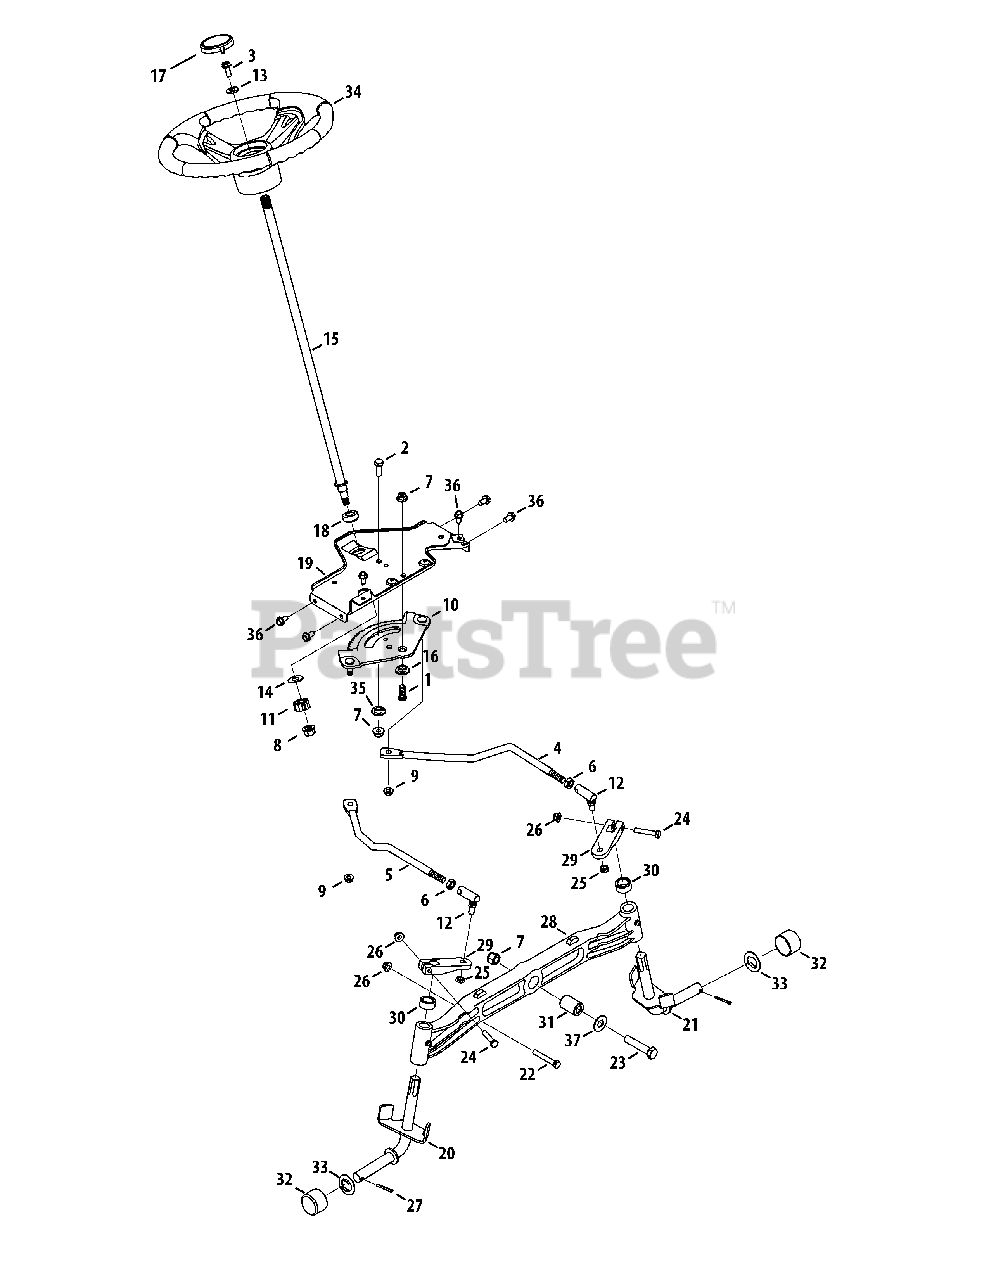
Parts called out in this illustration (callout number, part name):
1	Hex Screw, 3/8-16, 1.00, Gr5, Spec
2	Hex Screw, 3/8-16, 1.00, Gr5, Std
3	Hex Screw, 5/16-18, .875, Gr5, Lock
4	Link, Drag LH
5	Link, Drag RH
6	Nut, Jam, 7/16-20, Gr2
7	Nut, Flange Lock, 3/8-16, Grf,
8	Nut, Flange Lock, 7/16-20, Grb, Lock
9	Nut, Flange Lock, 5/16-18, Gr5, Sd Lk
10	Gear, Steering, 11/90 Ratio
11	Gear, Pinion, Steering
12	Ball Joint, 7/16-20, Lock
13	Washer, Flat, .406 x .875 x .105
14	Washer, Flat, .51 x 1.12 x .06
15	Shaft, Steering, .625 OD x 25, Cub
16	Spacer, Shoulder, .385x 1.25 x .3025
17	Cover, Steering Wheel, Cub Cadet
18	Bearing, Flange, Hex 5/8 Pm
19	Bracket, Support, Steering
20	Axle Ass’y, RH .750 Dia.
21	Axle Ass’y, LH .750 Dia.
22	Hex Screw, 5/16-18, 2.25, Gr5, Std
23	Hex Screw, 3/8-16, 2.50, Gr5, Std
24	Hex Screw, 5/16-18, 1.75, Gr5, Std
25	Nut, Hex Lock, 3/8-24, Grb
26	Nut, Flange Lock, 5/16-18, Grf
27	Pin, Cotter, 5/32, 1.25
28	Axle, Pivot Bar, Cast
29	Steering, Block
30	Spacer, .71 ID x .125 OD x .56
31	Spacer, .385 x 1.00 x 1.5075
32	Cap, Bumper
33	Washer, Flat, .350 x 1.559 x .062
34	Wheel, Steering, 3 Spoke, Softgrip
35	Spacer, .38 x 1.375
36	Screw, Self-tapping, 5/16-18, .750,
37	Washer, Flat, .406 x .875 x .059
